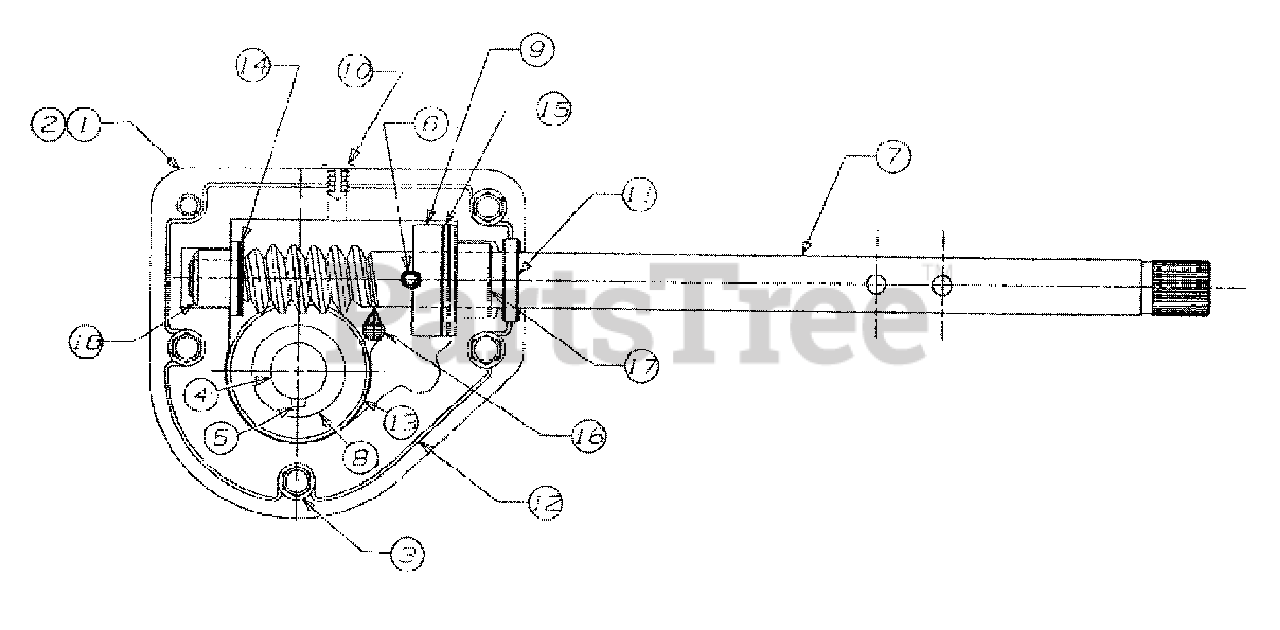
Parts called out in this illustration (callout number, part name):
1	Housing-R.H.
2	Housing-L.H.
3	Screw
4	Axle, Spiral 26" (753F)
4	Axle, Spiral 24" (733E)
5	Key, Hi-Pro
6	Pin, Spiral
7	Worm, Shaft
8	Gear, Worm
9	Collar, Thrust
11	Seal, Oil
12	Loctite 5699, Ultra
13	Washer
14	Washer
15	Washer
16	Grease
17	Bearing Flange
18	Bearing Flange
